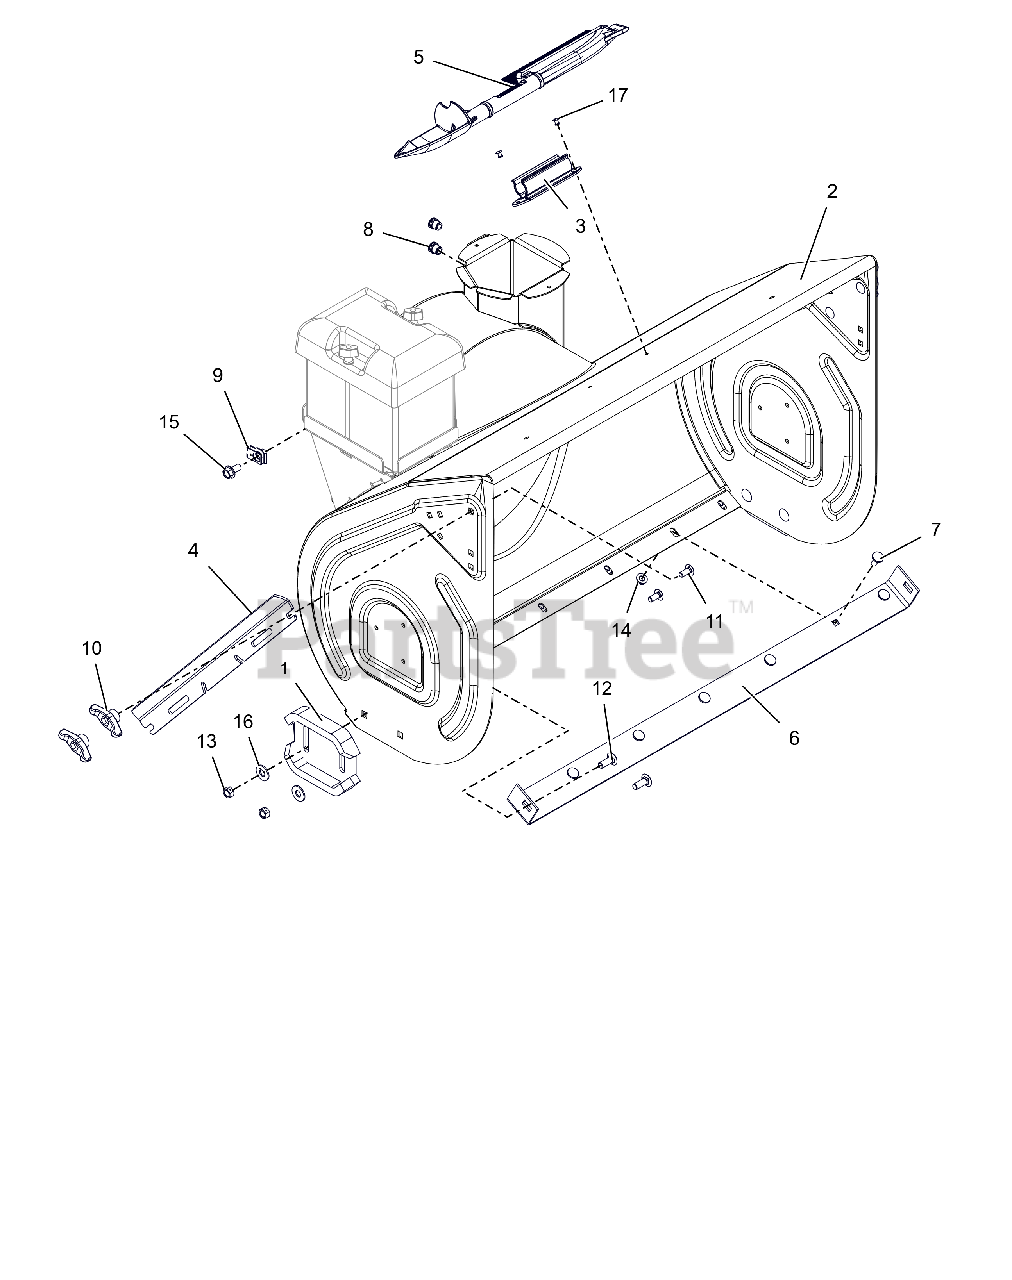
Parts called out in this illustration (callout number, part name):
1	RUNNER, SKID SHOE
2	BLOWER HOUSING W/DECAL 32" BAT
3	MOUNT, SNOW CLEAN OUT
4	CUTTER, DRIFT
5	DEVICE, SNOW CLEAN OUT W/BRUSH
6	BLADE, SCRAPER-32"
7	BOLT, MODIFIED HEAD CARRIAGE
8	NUT, THREADED INSERT .38-16
9	NUT-RTNR .375-16X.37
10	KNOB,WING .31-18 UNC NYL/TALC
11	@BLT-RHDSSQNK .31-18X.75 G5YZ
12	@BLT-RDHDSHSQNK.38-16X1.0 G5YZ
13	@NUT-LK-CTR .38-16 YWZC
14	@NUT-LK-TOP-FLG .31-18 YWZC
15	BLT-SERHFWH .38-16X.75 YWZC
16	@WSHR-FL-STL.438X1.00X.083 YWZ
17	RVT-POP .187 YZ
